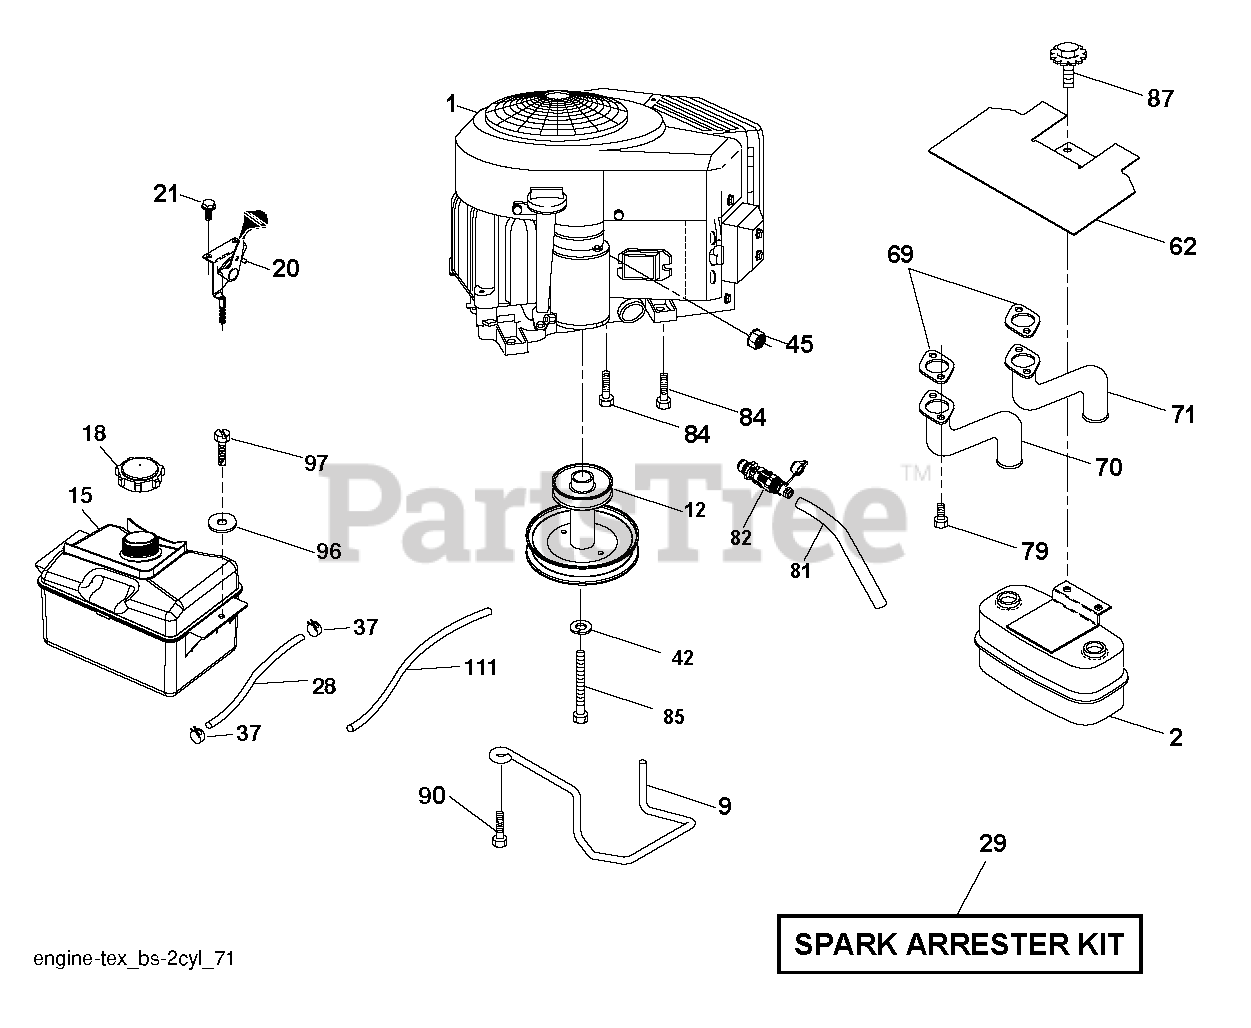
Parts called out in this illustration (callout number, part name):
2	MUFFLER.TWIN.CYL.LOW.TONE
9	KEEPER.BELT.ENGINE.4.2
12	RP_PULLEY ENGINE
15	TANK.ASM.FRT.2.5 GAL.W/CAP.EPA
18	CAP.FUEL.2 WAY VENT
20	CONTROL.TH/CK.COBRA.KO
21	SCREW.#10 X 0.750.BOS
28	LINE.FUEL.20"FRONT.EMI
29	KIT.SPARK ARRESTOR 794945 B&S
37	HOSE CLAMP
42	LOCKWASHER
45	NUT
62	SHIELD.HEAT.MUFFLER
69	GASKET.MUFFLER
70	RP.EXHAUST.TUBE.LH.BS/TWIN
71	EXHAUST.TUBE.RH.BS/TWIN
79	SCREW.SOCKET.HEAD.5/16-18
81	TUBE, DRAIN OIL ASM.
82	VALUE.OIL.DRAIN
84	SCREW.3/8-16
85	BOLT HEX 7/16-20X4-1/4"
87	BOLT 5/1618UNC X 3/4 W/ SEMS
90	SCREW 3/8-16X1
96	WASHER
97	SCREW HEXWSHR 1/4-20X3/4
111	RP PURGE LINE
